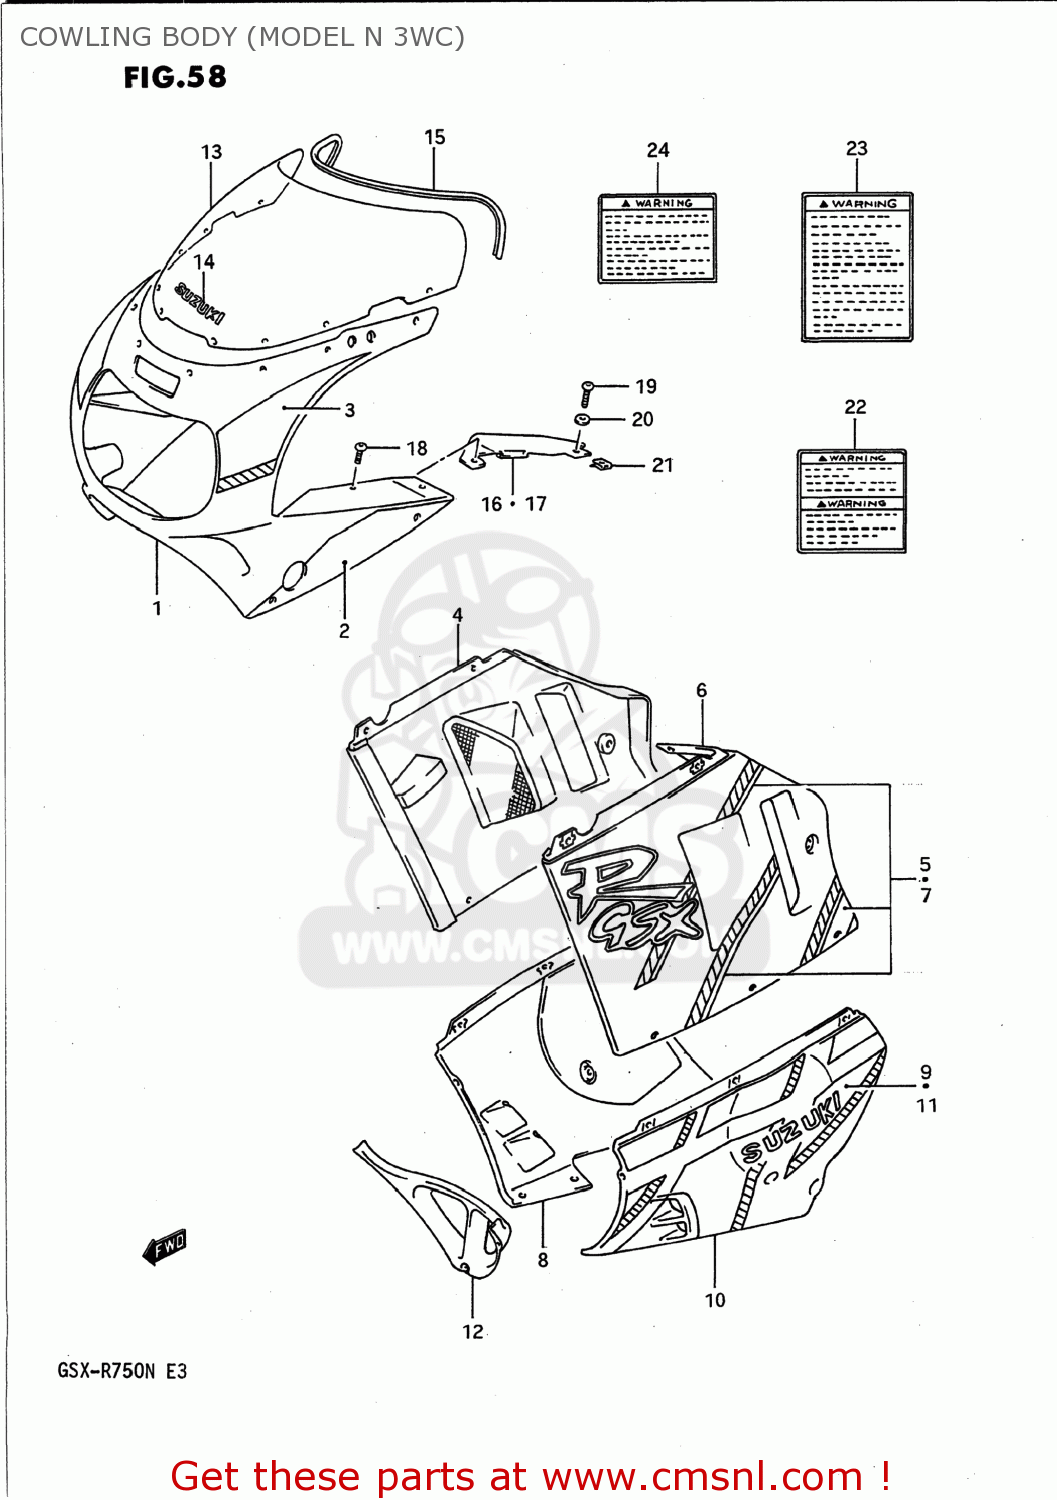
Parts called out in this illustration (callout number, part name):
1	BODY ASSY,COWLING
2	TAPE SET,COWLING,UPPER SIDE
3	TAPE SET,COWLING,UPPER,FRONT
4	COVER,COWLING SIDE,RIGHT (B
5	TAPE SET,COWLING SIDE,RIGHT
6	COVER COMP,COWLING SIDE,LEFT
7	TAPE SET,COWLING SIDE,LEFT
8	COWLING COMP,UNDER,RIGHT
9	TAPE SET,COWLING,UNDER STRIPE
10	COWLING COMP,UNDER,LEFT
11	TAPE SET,COWLING,UNDER STRIPE
12	COWLING,UNDER,CENTER (B
13	SCREEN SET,WINDOW
14	EMBLEM,WINDSCREEN
15	MOLDING,WINDSCREEN
16	PANEL,COWLING UPR,R
17	PANEL,COWLING,UPPER,LEFT
18	SCREW(5X10)
19	SCREW(5X14)
20	WASHER(5.2X11X1)
21	NUT
22	LABEL (WARNING)
23	LABEL (WARNING SCREEN)
24	LABEL
